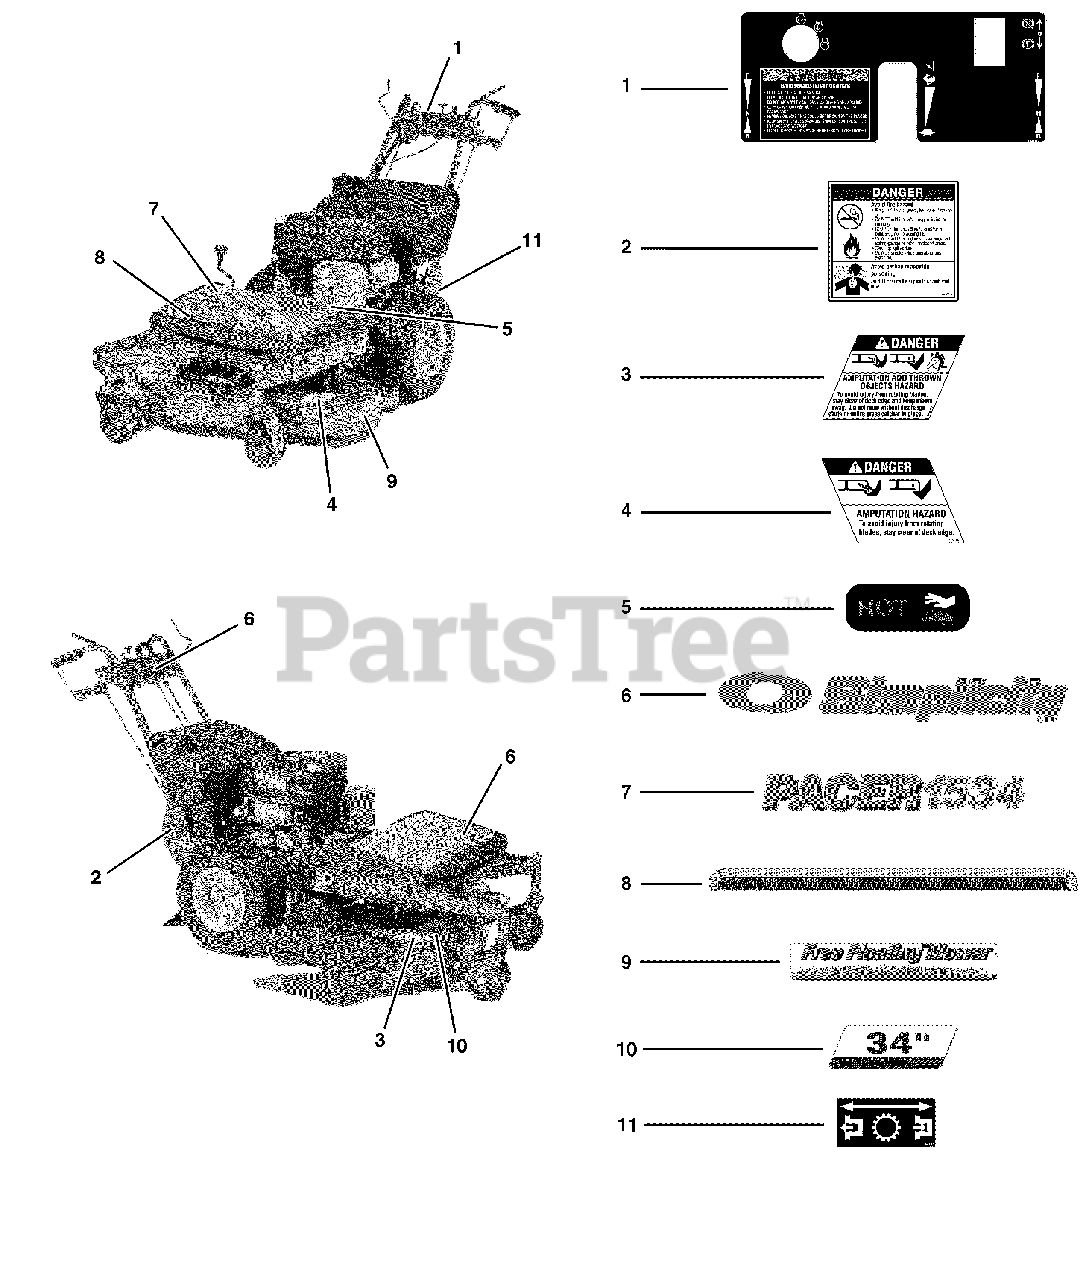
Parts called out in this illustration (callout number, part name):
1	DECAL, Control Panel
2	DECAL, Danger
3	DECAL, Danger, Mower Discharge
4	DECAL, Danger, Mower
6	DECAL, Simplicity, Silver & Blue, W/Icon
7	DECAL, Pacer 1534
8	DECAL, Stripe, Blue & Silver
9	DECAL, Free Floating
11	DECAL, HYDRO RELEASE
12	* MODEL/SERIAL TAG
13	* DECAL, OPEI
